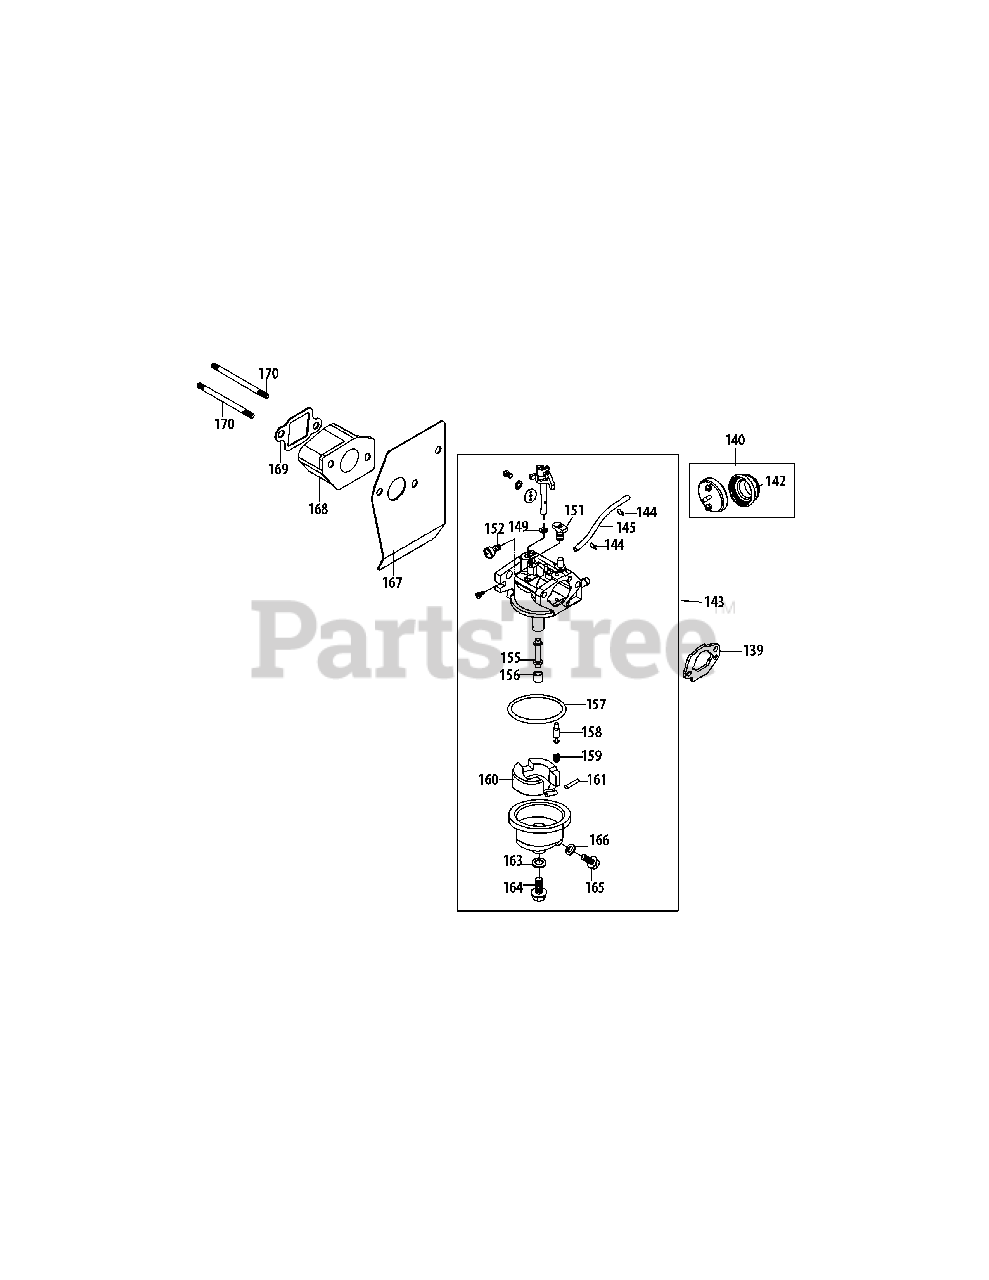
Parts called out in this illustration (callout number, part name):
139	Carburetor Gasket Plate
140	Primer Assembly
142	Primer Bulb
143	Carburetor Assembly
144	Primer Hose Clamp
145	Primer Hose
149	Throttle Shaft Fiber O-Ring
151	Idle Jet Assembly
152	Idle Speed Adjusting Screw
155	Emulsion Tube
156	Main Jet
157	Fuel Bowl O-Ring
158	Needle Valve
159	Needle Valve Spring
160	Float
161	Float Pin
163	Fuel Bowl Gasket
164	Fuel Bowl Mounting Bolt
165	Fuel Drain Plug
166	Fuel Drain Plug Gasket
167	Carburetor Gasket
168	Carburetor Insulator
169	Carburetor Insulator Gasket
170	Carb Stud M6x113
